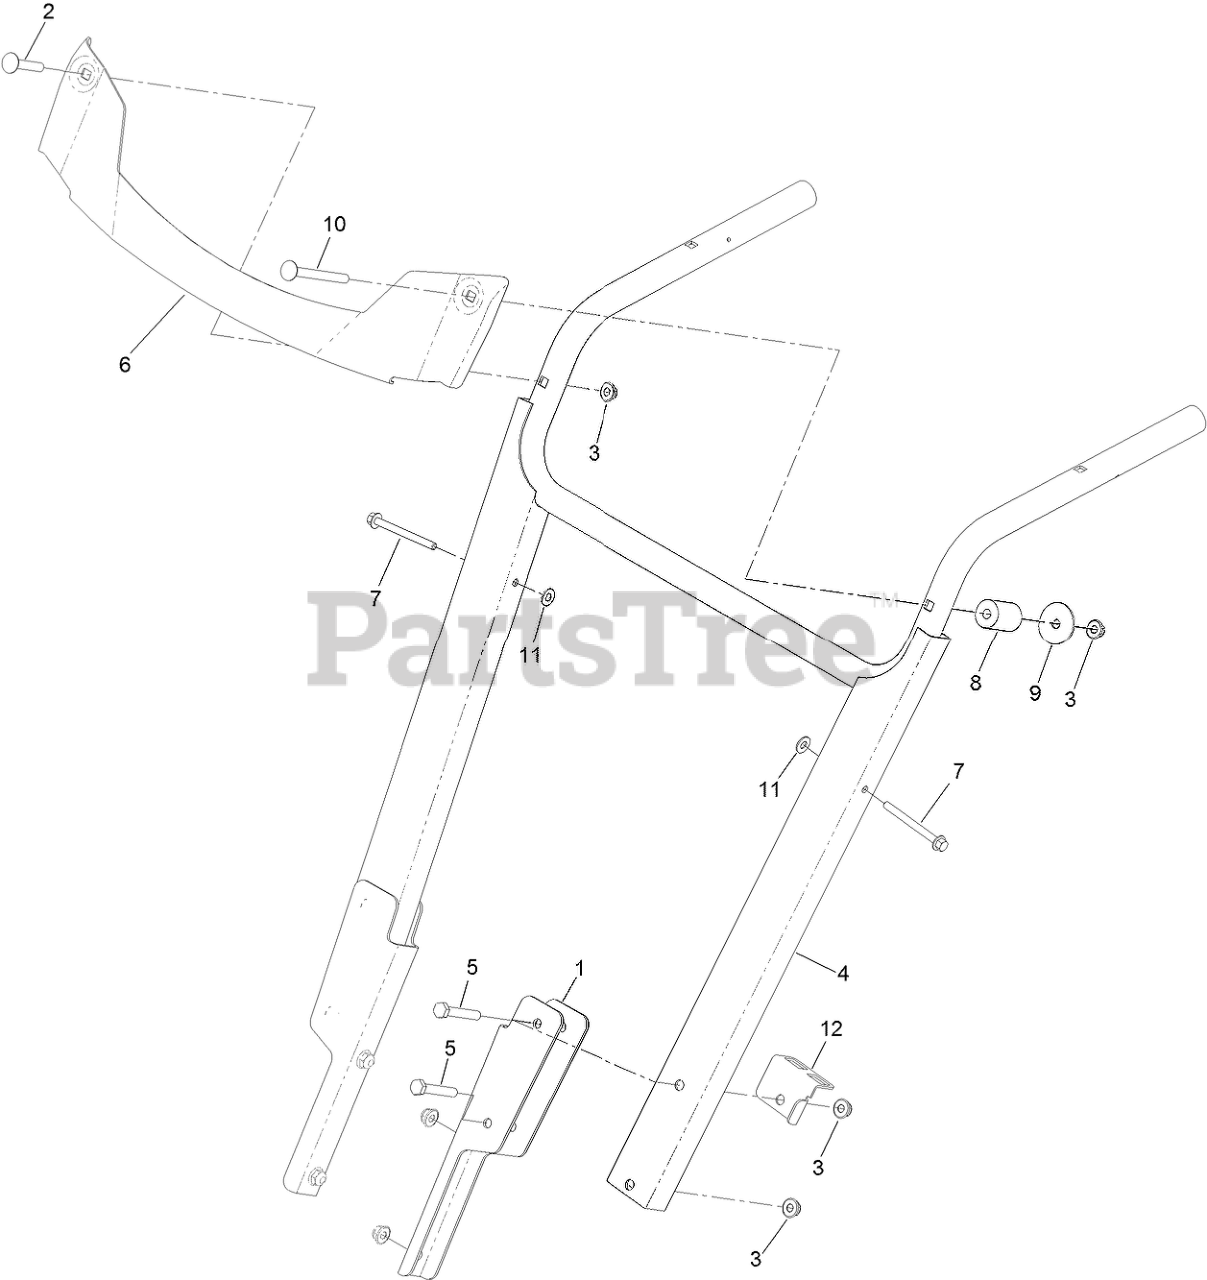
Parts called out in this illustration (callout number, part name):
1	BRACKET-HANDLE, LOWER
2	BOLT-CARR
3	NUT-HF
4	HD HANDLE ASM
5	SCREW-HH
6	TRIM-METAL, HD
7	SCREW-HHF
8	SPACER
9	WASHER-FLAT
10	SCREW-CARR
11	WASHER-PLAIN
12	BRACKET-STICK, CLEANOUT
